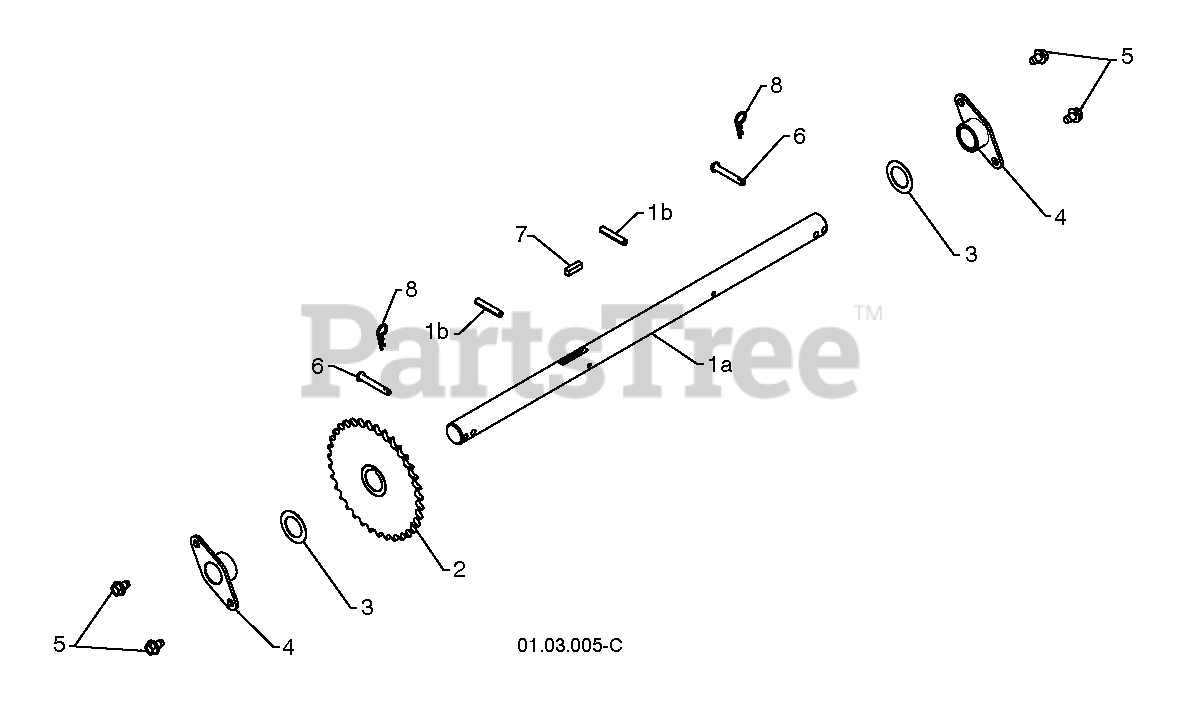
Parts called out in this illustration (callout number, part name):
1	AXLE.SHAFT.ASM.W/ROLPIN.NON-PS
2	SPROCKET.WELDMENT.AXLE.1.00
3	WASHER 1.00
4	BEARING, AXLE
5	SCREW LT
6	RIVET
7	KEY, SQUARE 1/4 X .875
8	RETAINER M
